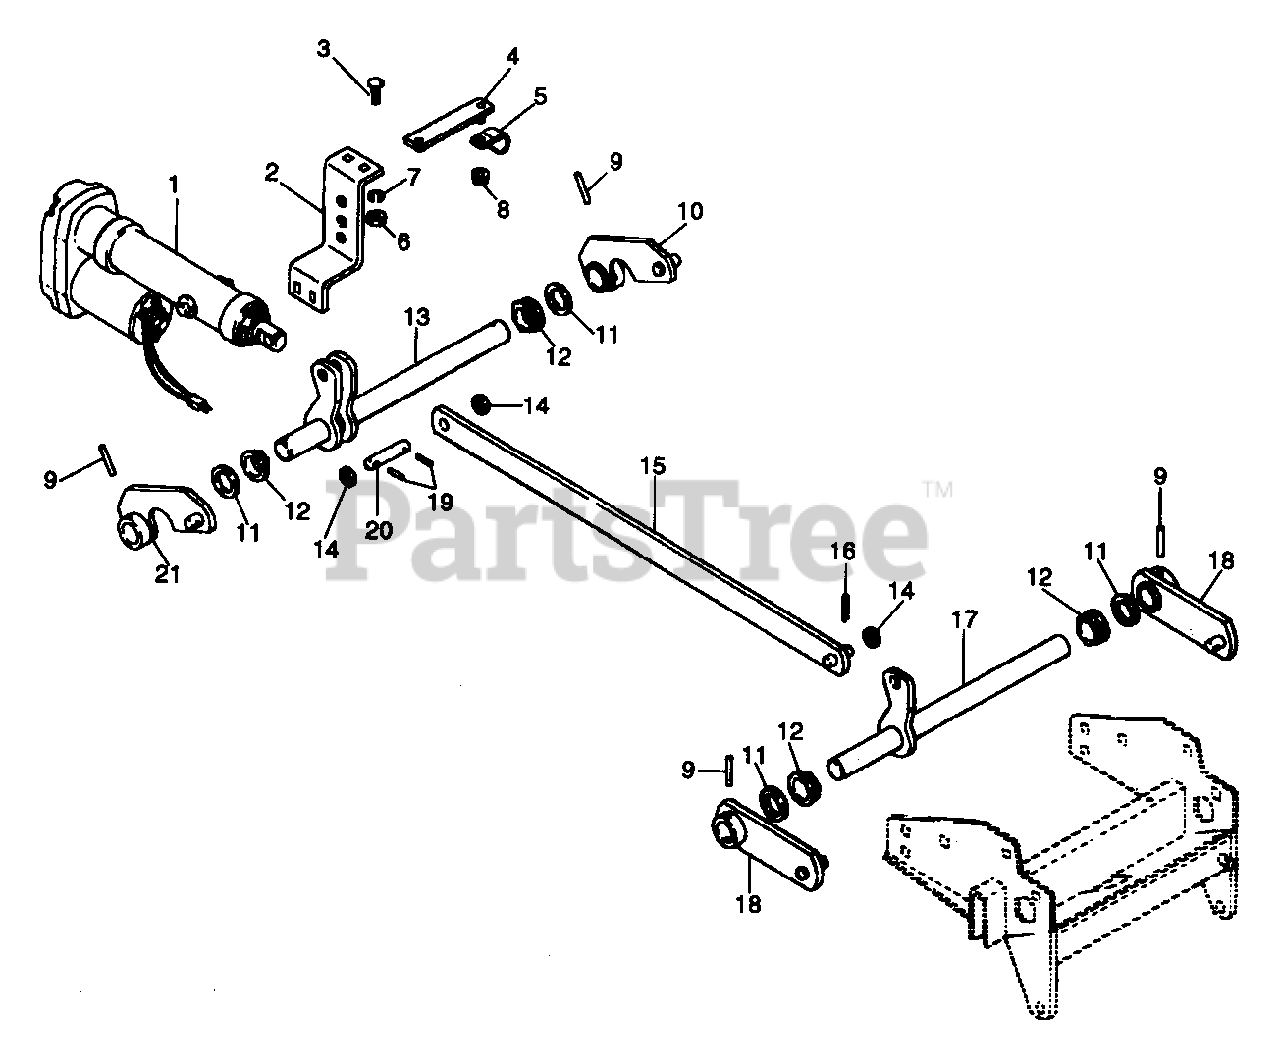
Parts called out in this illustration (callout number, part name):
1	ACTUATOR
2	BRACKET-ACTUATOR
3	BLT-RDHDSQNK .31-18X1.00 PL
4	BRACKET
6	NUT-HEX .312-18
7	WSHR-LK .312X.097 PL HVY
8	NUT-FLG. .312-18 PL
9	PIN-GRV .250X1.50 TP A
10	LIFT ARM LH
11	WSHR-FL-STL 1.015X1.500X.125
12	BSHG-FLG 1.000X1.25X.49X1.56HX
13	LIFT PIVOT
14	WSHR-FL-STL .520X.827X.062 YZ
15	LIFT LINK
16	PIN-COTR .18X1.0 PL
17	FRONT PIVOT
18	LIFT ARM - FRONT
19	PIN-ROLL .188X1.00
21	LIFT ARM RH
